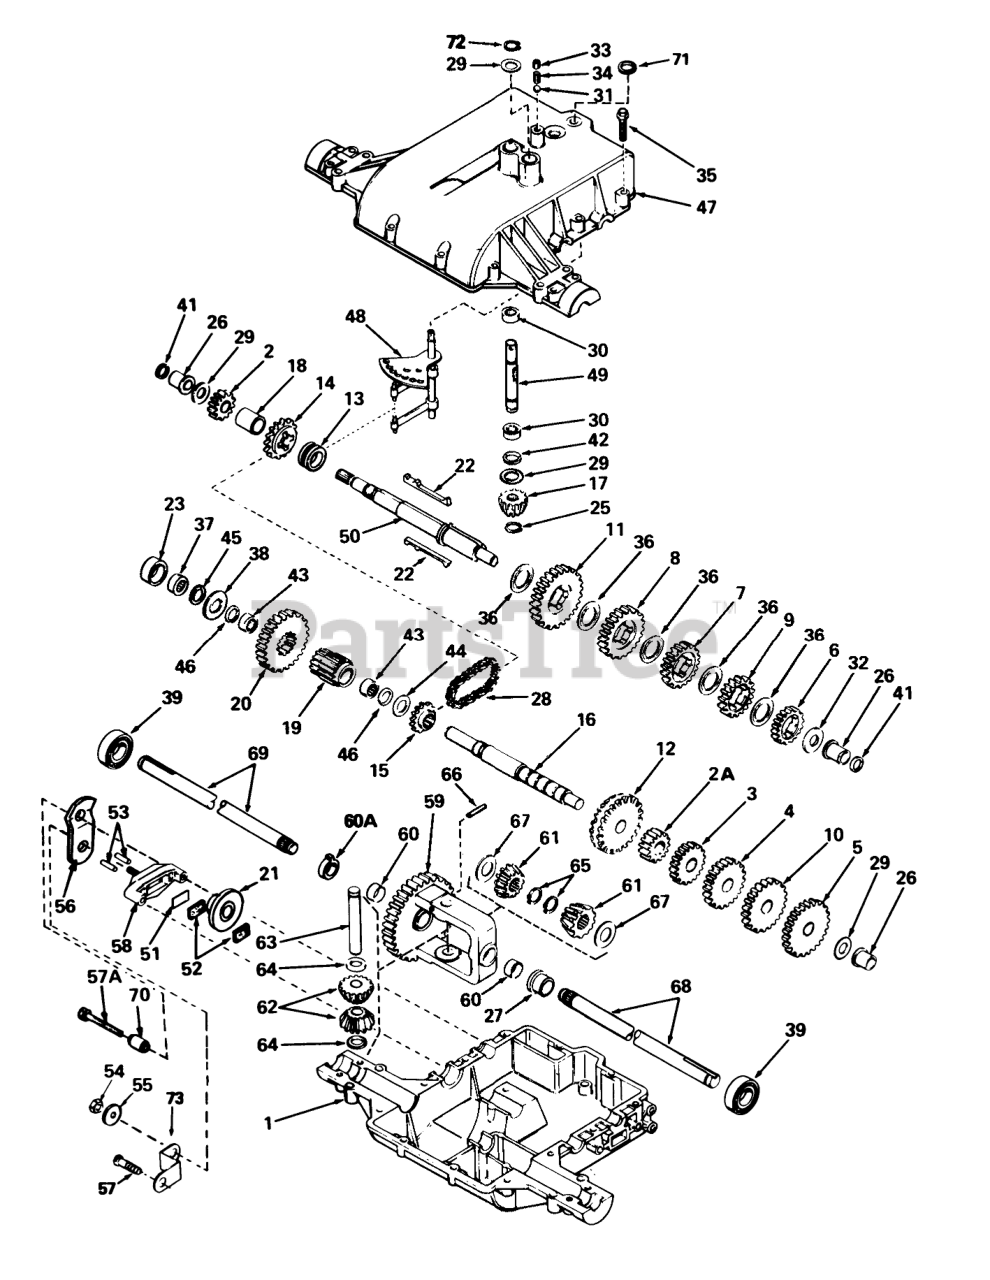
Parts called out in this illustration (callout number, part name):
1	Case-transaxle
2	Gear-Spur 15 Teeth
2A	Gear-Spur, 12 Teeth
3	Gear-Spur, 20 Teeth
4	Gear-Spur, 25 Teeth
5	Gear-Spur (30 teeth)
6	Gear-Spur 20 teeth
7	Gear-Spur, 25 Teeth
8	Gear-Spur, 30 Teeth
9	Gear-Spur (22 teeth)
10	Gear-Spur (28 teeth)
11	Gear-Spur, 37 Teeth
12	Gear-Bevel (42Teeth)
13	Collar-Shift
14	Sprocket-18 Teeth
15	Sprocket-9 Teeth
16	Shaft-Counter
17	Bevel Pinion-Input
18	Spacer
19	Pinion-Output
20	Gear-Output
23	Spacer
25	Ring-Retainer
26	Bushing-Flange
27	Bushing-Flanged
28	Chain-Roller #41
29	Washer
30	Bearing-Needle
31	Ball-Steel
32	Washer
33	Screw-Set
34	Spring
35	Ring Set (.020 O S)
36	Washer
37	Bearing-Needle
38	Washer-Flat
39	Bearing-Ball
41	Ring-Square Cut
42	O Ring
43	Bearing-Needle
44	Washer-Flat
45	Ring-Square Cut
46	Ring-Square Cut
47	Cover-Transaxle
48	Rod & Fork Assembly
49	Shaft-Input
50	Shaft-Brake
51	Brake Pad Plate
52	Brake Pad
53	Dowel Pin
54	Locknut
55	Washer
56	Lever-Brake
57	Ring Set (.020 O S)
57A	Screw-Hex. Flange
58	Holder-Brake Pad
59	Gear Assy.-Differential (Incl. 2 of Ref. #60)
60	Bushing
60A	Bushing
61	Gear Bevel
62	Gear Pinion
63	Drive Pin
64	Thrust Washer
65	Ring-Snap
66	Pin-Roll
67	Washer
68	Axle (14 7/8" Long)
69	Axle (13" Long)
70	Spacer
71	Cut Seal-Square
72	Ring-Snap
73	Bracket-Brake Lever
